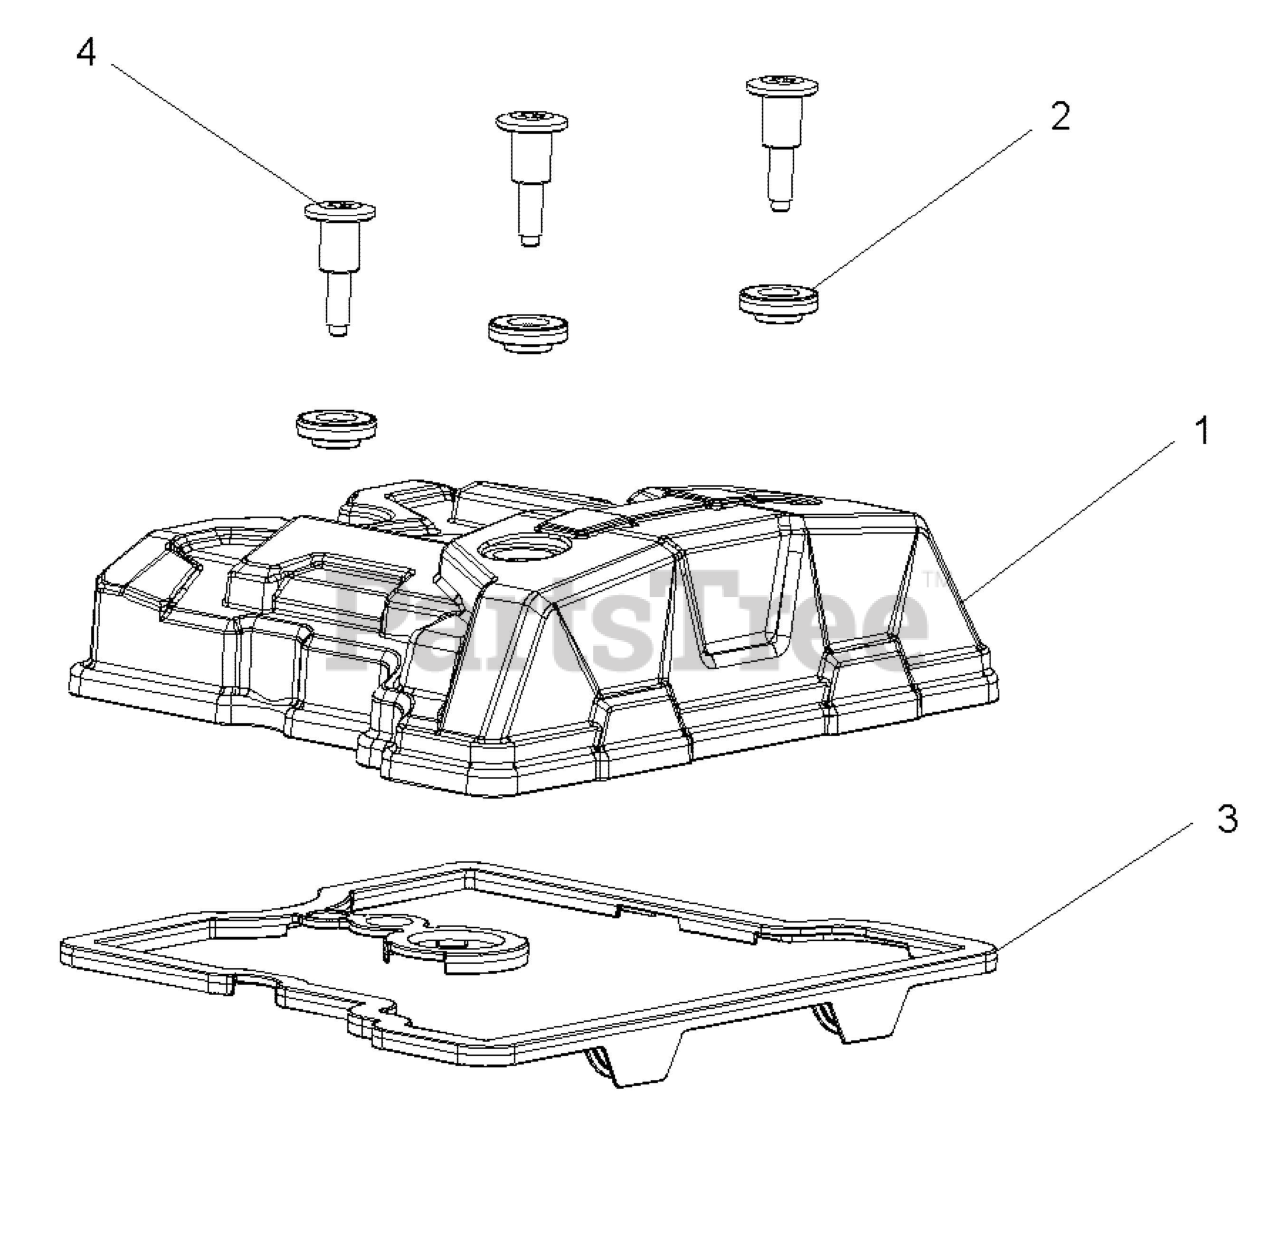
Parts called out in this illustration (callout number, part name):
1	COVER-VALVE,CAST,1CYL,DOHC
2	ISOLATOR-VALVE COVER
3	SEAL, VALVE COVER,1CYCL,DOHC
4	BOLT-SHLDR,M6X12X15
